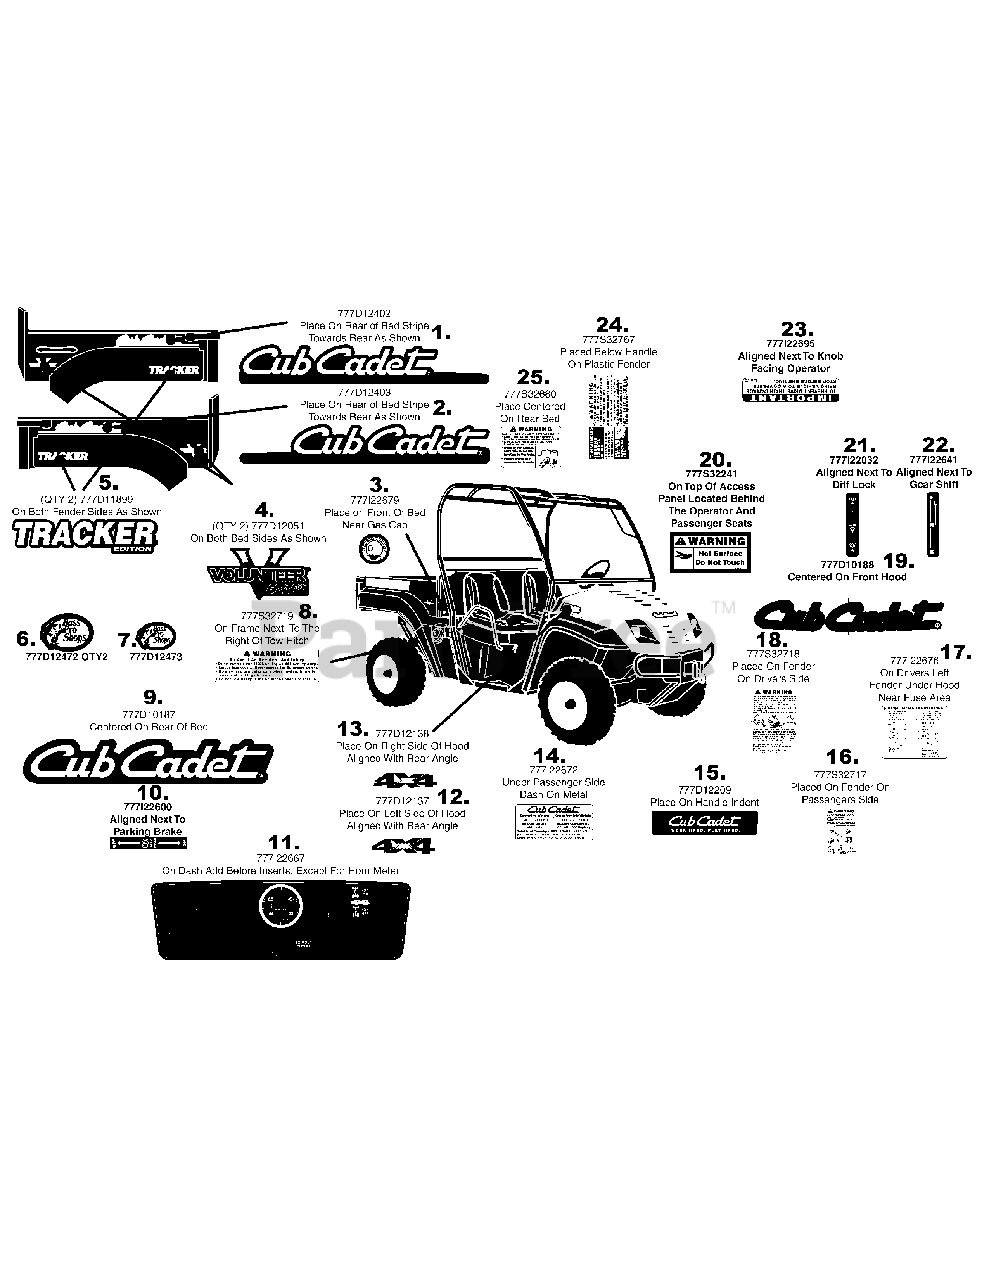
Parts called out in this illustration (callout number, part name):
1	LABEL:UV:CUB CAMO EURO:LEFT
2	LABEL:UV:CUB CAMO EURO:RIGHT
3	LABEL-CHECK ENG OIL
4	LABEL-UV VOL OLIVE GREEN 624
5	LABEL:UV:TRACKER FENDERS
6	LABEL:UTILITY:BASSPRO LARGE
7	LABEL:UTILITY:BASSPRO SMALL
8	LABEL-TOW HITCH
9	LABEL-CUB CADET BED
10	LABEL-PARK BRAKE
11	LABEL-DASH
12	LABEL:CUB UV:4X4 HOOD LT SD EFI
13	LABEL:CUB UV:4X4 HOOD RT SD EFI
14	LABEL-OPERATING WGT
15	LABEL-UV DASH LOGO CAMO
16	LABEL-RIDER FALL RH FENDER
17	LABEL:UV:4X4 KOHLER FUSE
18	LABEL-ROLL & FALL LH FENDER
19	LABEL-CUB CADET HOOD
20	LABEL-HOT SURFACE
21	LABEL-DIFF LOCK CO
22	LABEL-GEAR SHIFT
23	LABEL:4X4 SHIFT
24	LABEL-4X4 CARGO BOX HANDLE
25	LABEL-CARGO LOAD
